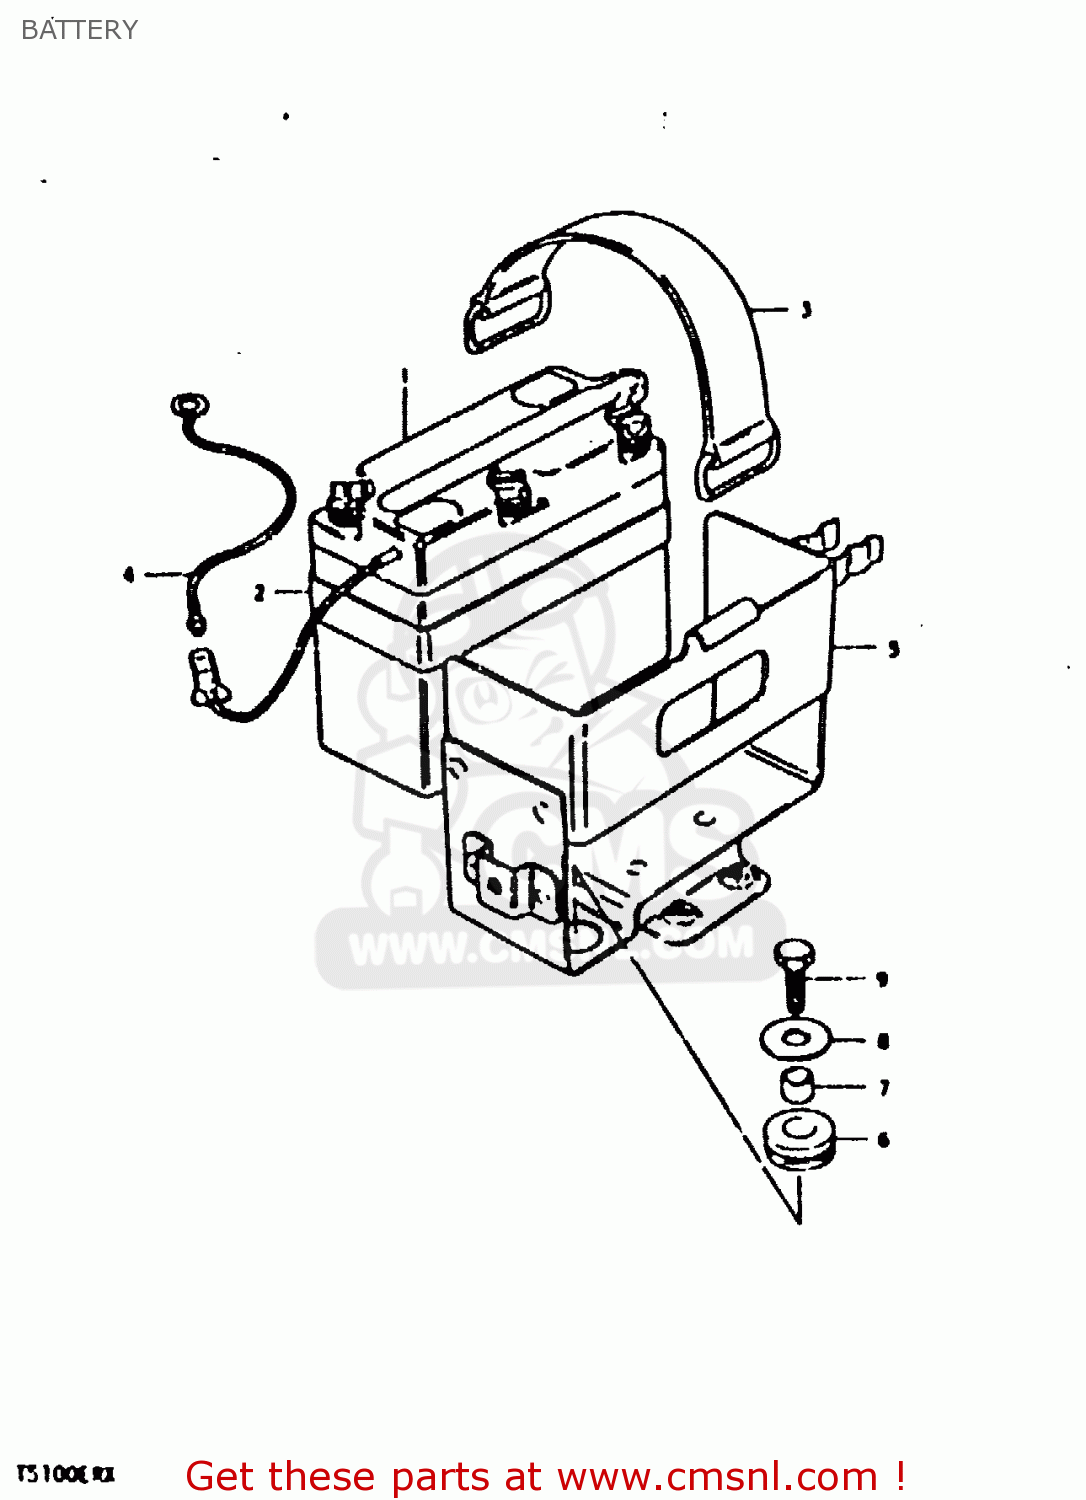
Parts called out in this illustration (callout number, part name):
1	BATTERY(6N4B-2A,6V4.2AH)
2	PROTECTOR,BATTERY
3	BAND
4	LEAD WIRE
5	HOLDER,BATTERY
6	CUSHION
7	SPACER (7*9*7)
8	WASHER (6.5X20X1.2)
9	BOLT, UPPER
